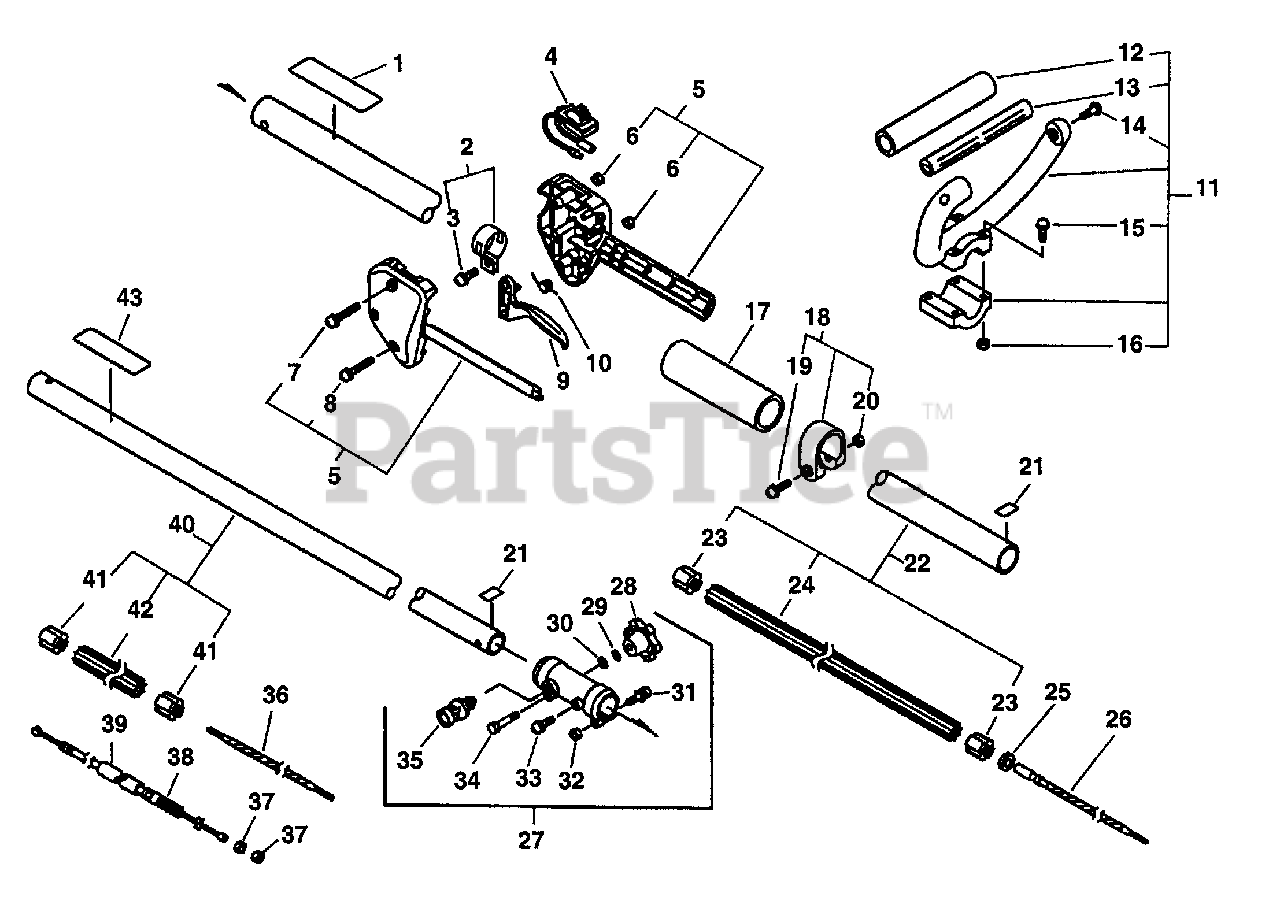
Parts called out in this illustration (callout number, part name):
1	Label, caution
2	Band asy
3	Screw 5x14
4	Switch, ignition
5	Bracket set, throttle
7	Screw 5x35
8	Screw 5x25
9	Control, throttle
10	Spring, throttle return
11	Handle asy, loop
12	Grip, front handle
13	Handle, front
14	Screw 5x30
15	Screw 5x35
17	Grip, rear handle
18	Band
19	Screw 5x28
21	Label, location
22	Housing asy, d. Shaft (upper)
24	Liner, flexible (upper)
25	Cushion
26	Shaft, flexible (upper)
27	Bracket asy
28	Locknut
29	Washer, spring 5
30	Washer 5
31	Bolt 5x30 (w/w,sw)
33	Screw 5x12
34	Bolt 5x35
35	Latch asy
36	Shaft, flexible (lower)
38	Wire, throttle
40	Housing asy, d. Shaft (lower-srm)
42	Liner, flexible (lower)
43	Label, caution
